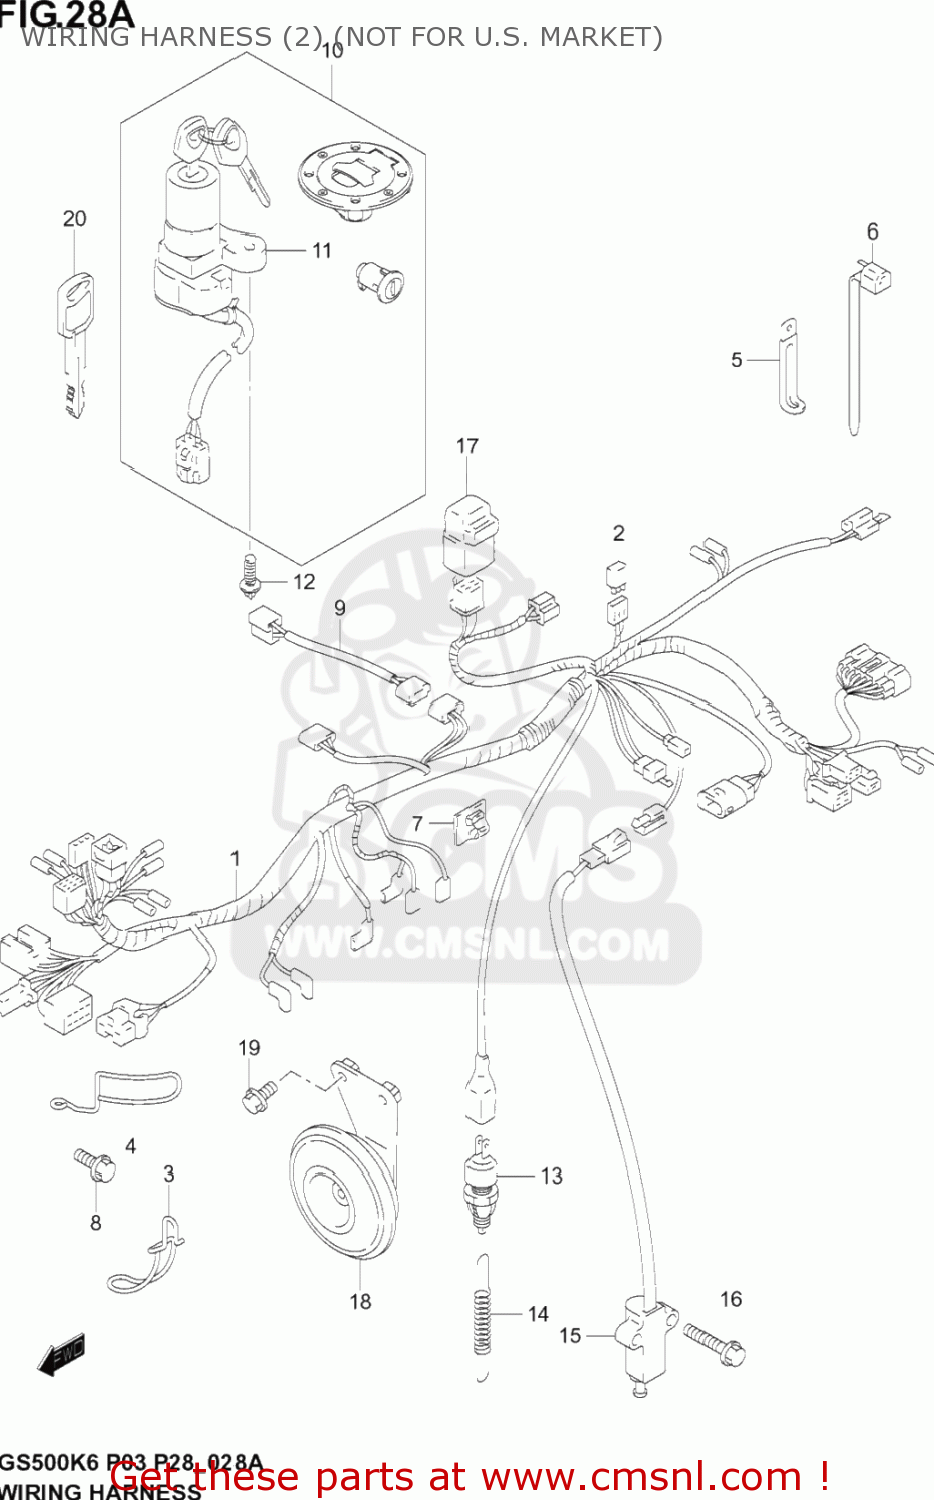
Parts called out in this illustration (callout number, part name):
1	HARNESS, WIRING
2	DIODE
3	PROTECTOR
4	PROTECTOR
5	CLAMP(L:45)
6	CLAMP
7	CLAMP
8	BOLT
9	WIRE,AIR SOLENOID
10	LOCK SET
11	LOCK ASSY,STEERING
12	SCREW(6X18)
13	SWITCH ASSY,STOP LAMP
14	SPRING
15	SWITCH ASSY,SI
16	BOLT
17	RELAY ASSEMBLY
18	HORN ASSY
19	BOLT OIL LEVEL
20	KEY,BLANK
